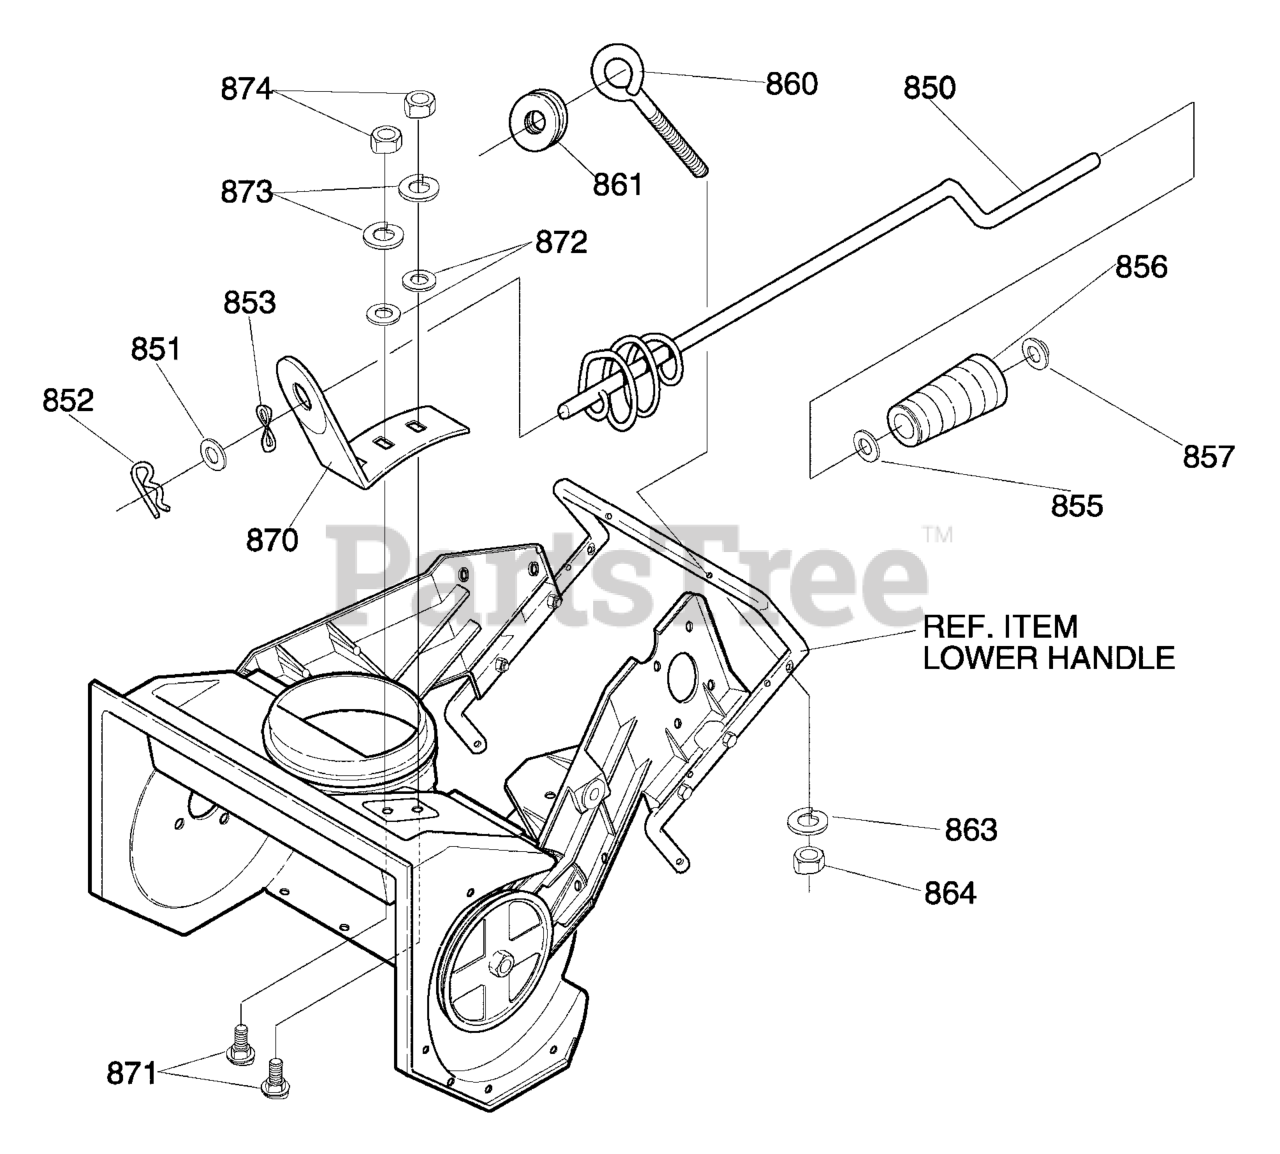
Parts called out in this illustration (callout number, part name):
850	ROD, CHUTE
851	WASHER, FLAT
852	PIN, COTTER
853	WASHER CURVED
855	WASHER, FLAT
856	KNOB, SLEEVE
857	NUT, PUSH
860	BOLT, EYE 3/8-16X2.00
861	GROMMET, EYE BOLT
870	BRACKET, CHUTE
871	BOLT, 5/16-18X.75
872	WASHER, FLAT
873	WASHER
874	NUT, 5/16-18
